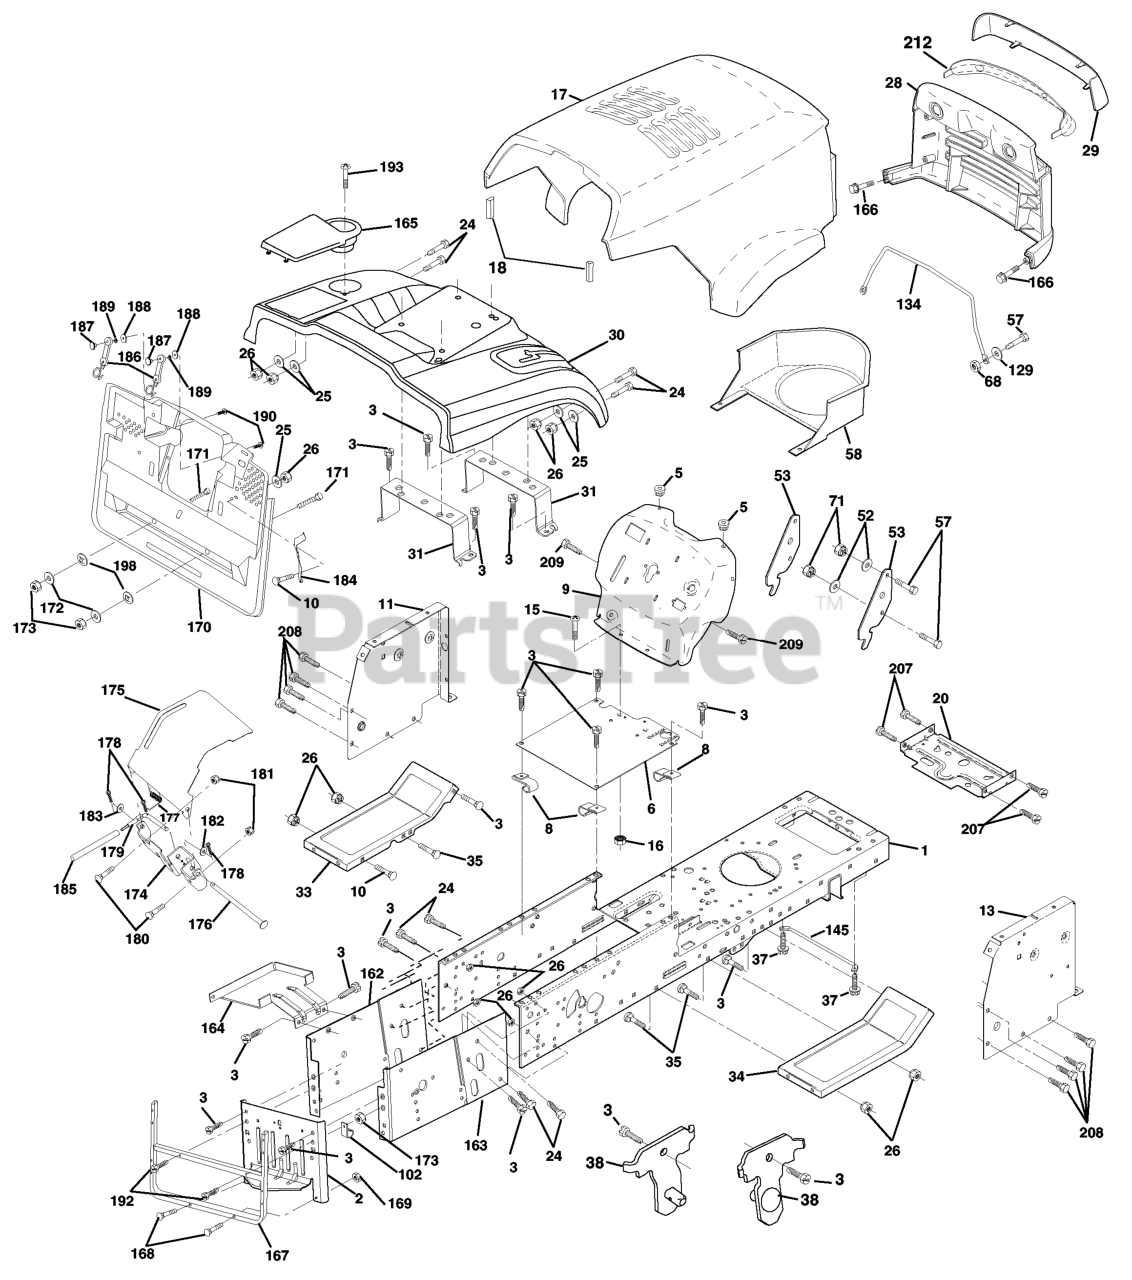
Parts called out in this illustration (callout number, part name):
1	CHASSIS STAMPING
3	SCREW 3/8-16X3/4
5	BUMPER.RUBBER.HOOD
6	SADDLE FLAT
8	CLIP,INSULATOR
10	BOLT D
11	PANEL DASH LH
13	DASH PANEL RH
15	Screw, Machine, Truss Head 5/16-18 UNC x 3/4
16	NUT
17	HOOD
18	BUMPER HOOD T
20	PLATE MTG
24	BOLT
25	WASHER
26	NUT
28	GRILL
29	LENS
31	BRACKET SUPPORT FENDER
33	FOOT REST LH
34	FOOTREST RH
35	BOLT
37	Screw Thdrol 5/16-18 x 1/2 TYT
38	BRACKET
52	WASHER
53	BRACKET PNT PICK OFF LT/PL
57	BOLT
58	AIR DUCT P/L/LT
68	NUT
71	NUT.CROWNLOCK.1/4
102	CLIP T
129	WASHER
134	ROD SUPPORT HOOD LT/PL HUS.
145	ROD PIVOT CHASSIS/HOOD
165	COVER BATTERY
166	SCREW
167	SUPPORT.ASM.BACKPLATE
168	BOLT.ROUND.HEAD.SQUARE.NECK
169	NUT T
170	COVER BACKPLATE
171	Bolt Hex 3/8-16 x 2-1/2 Gr. 5
172	WASHER
176	HINGE PIN
177	SPRING COVER LH
178	COTTER PIN
180	BOLT RB
181	LOCKNUT
183	WASHER
185	TUBE LEVER
186	LATCH ASSY
187	WELDNUT
189	LOCKWASHER #10
190	SCREW
192	SCREW LT
193	Screw Truss 1/4-20 x 3/4 Tap/R
207	SCREW, 5/16-18 X 1/2
208	SCREW 3/8-16X1/2
209	SCREW, 3/8-16X3/4
212	INSERT LENS REFLECTOR
